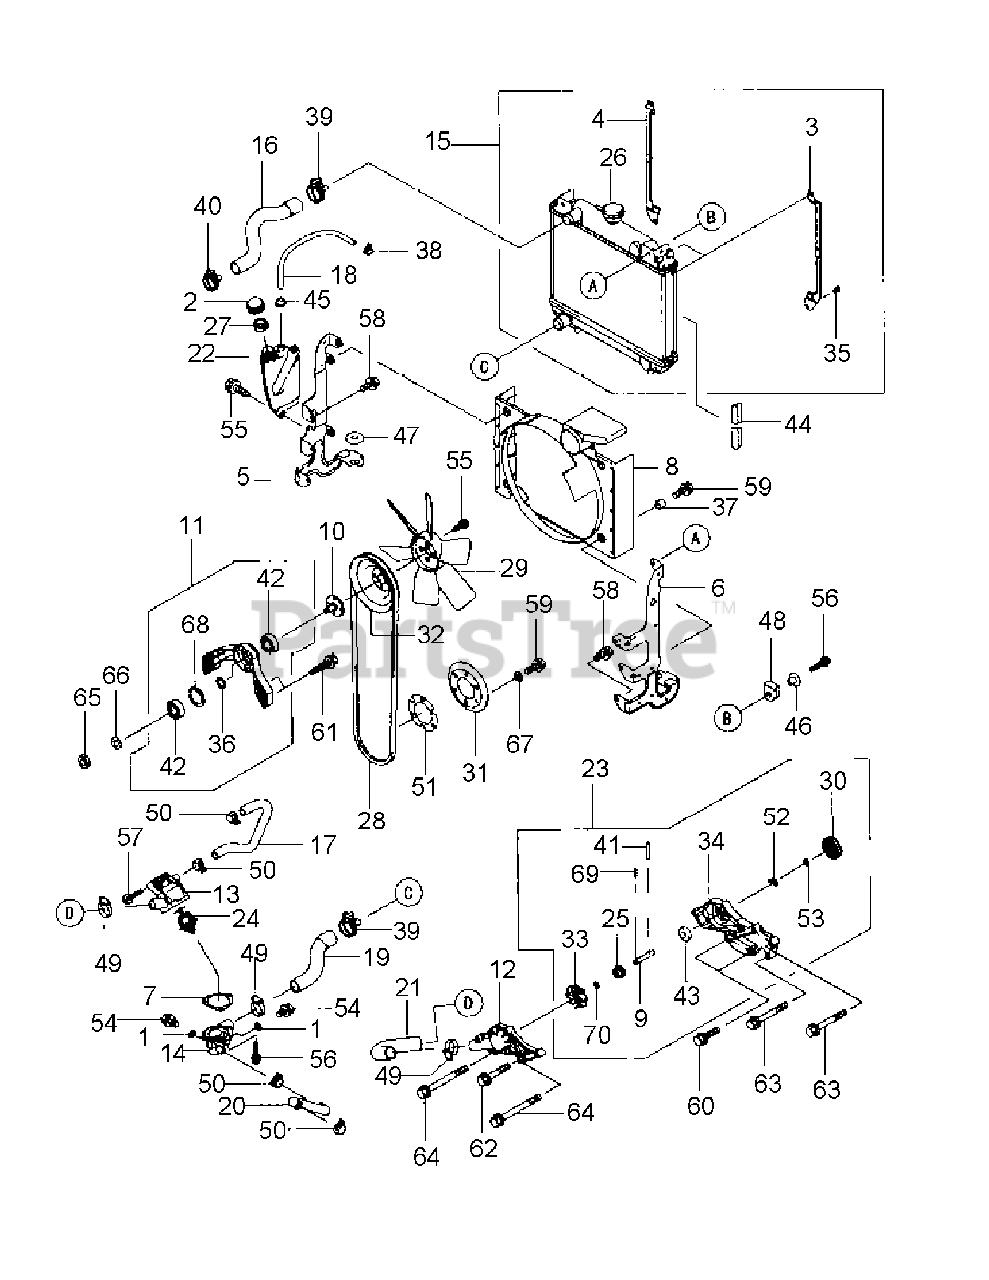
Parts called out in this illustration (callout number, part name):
3	SCREEN BRACKET
4	SCREEN BRACKET
5	RADIATOR BRACKET
7	THERMOSTAT GASKET
8	FAN GUIDE
9	IMPELLAR SHAFT
11	HOUSING ASSY.
13	UPPER BODY
15	RADIATOR ASSY.
17	COOLING HOSE
25	MECHANICAL SEAL
27	CAP BREATHER ELEMENT
30	SPUR GEAR 25T
40	CLAMP
42	BALL BEARING
45	HOSE TANK SEAL
46	COLLAR
47	RADIATOR DAMPER, LOWER
48	RADIATOR DAMPER, UPPER
51	SHIM, .06
51	SHIM, 1.2
54	FLANGED BOLT
55	FLANGED BOLT
56	FLANGED BOLT
57	FLANGED BOLT
58	FLANGED BOLT
59	FLANGED BOLT
60	FLANGED BOLT
61	FLANGED BOLT
62	FLANGED BOLT
63	FLANGED BOLT
64	FLANGED BOLT
65	HEX NUT, FINE
66	PLAIN WASHER
67	SPRING WASHER
